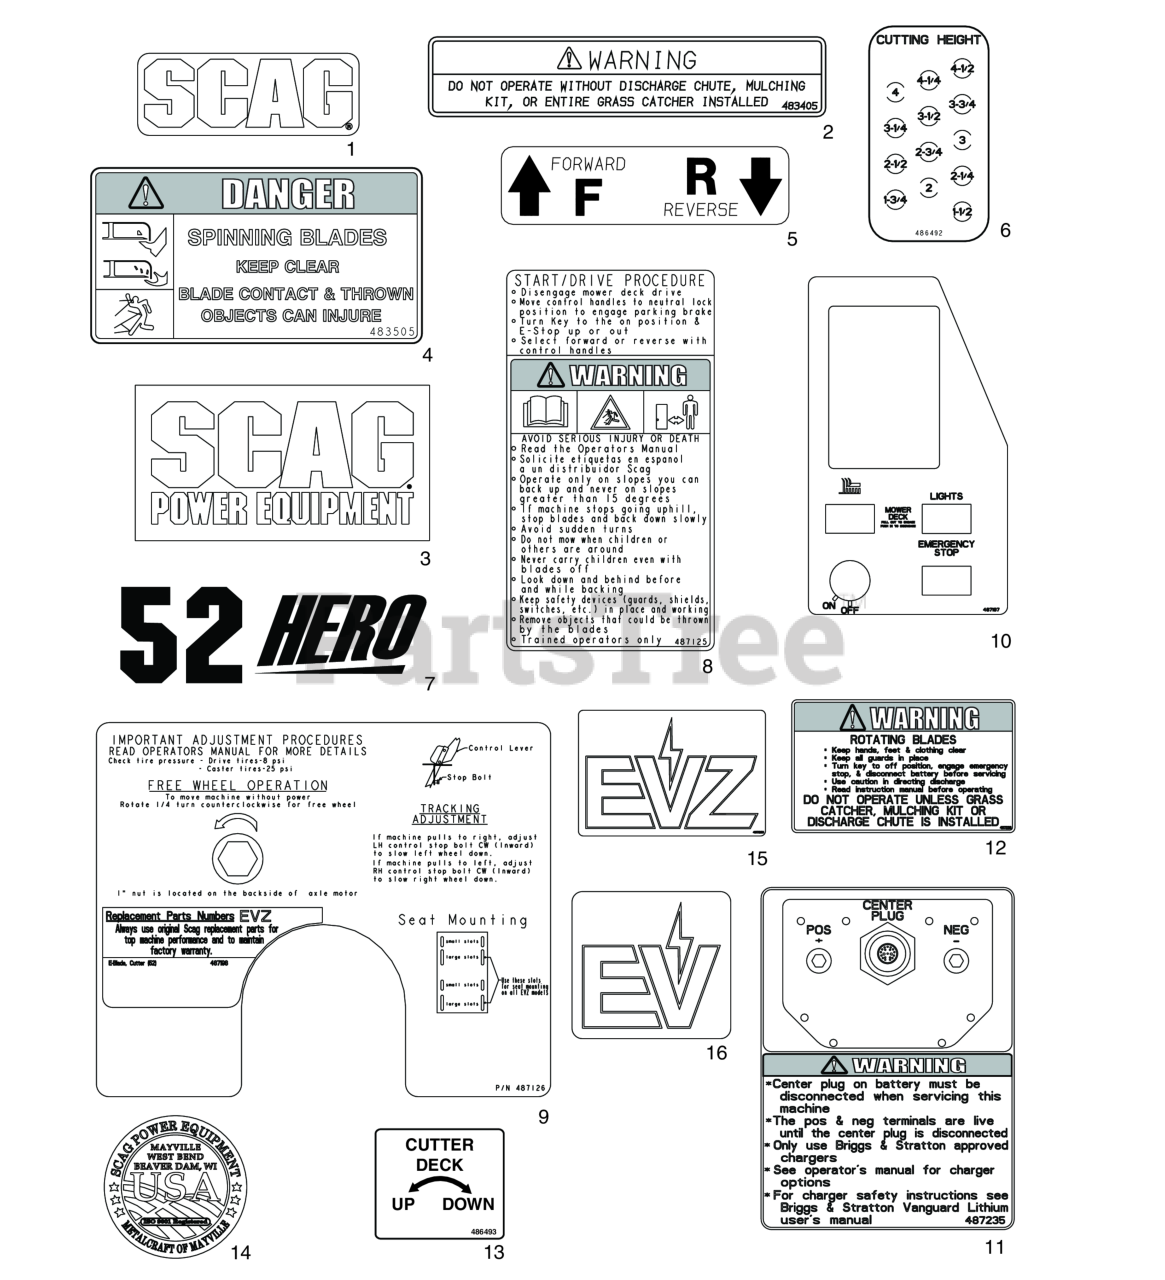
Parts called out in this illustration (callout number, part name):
1	Decal, Scag
2	Decal, Warning-Discharge
3	Decal, Scag Power Equipment
4	Decal, Spinning Blades
5	Decal, Traction Control
6	Decal, Height of Cut
7	Decal, 52 Hero
8	Decal, Start / Drive
9	Decal, SEVZ Adjustments / Replacement Parts
10	Decal, SEVZ Instrument Panel
11	Decal, Warning / Caution
12	Decal, Knives
13	Decal, Cutter Deck Lift Control
14	Decal, Metalcraft - USA
15	Decal, SEVZ
16	Decal, EV
